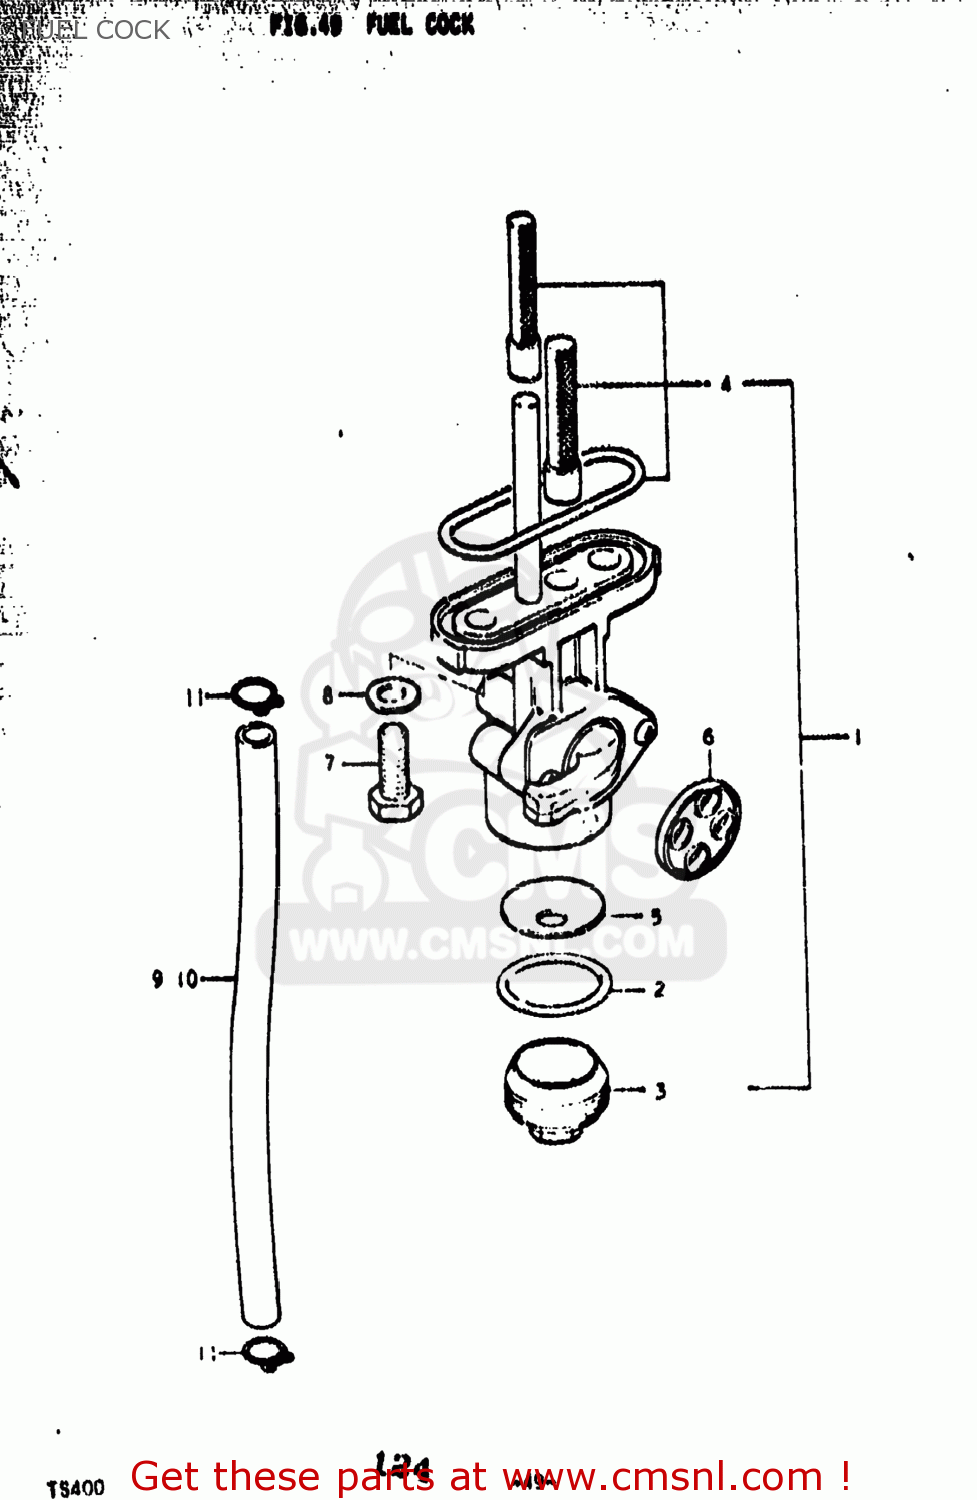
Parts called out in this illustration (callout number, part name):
1	COCK ASSEMBLY,FUEL
2	GASKET,FILTER (NAS)
3	CUP,FUEL COCK STRAINER
4	FILTER SET,FUEL COCK
5	NET,STRAINER
6	GASKET,LEVER (NAS)
7	SCREW
8	GASKET
9	HOSE
10	HOSE
11	CLIP
